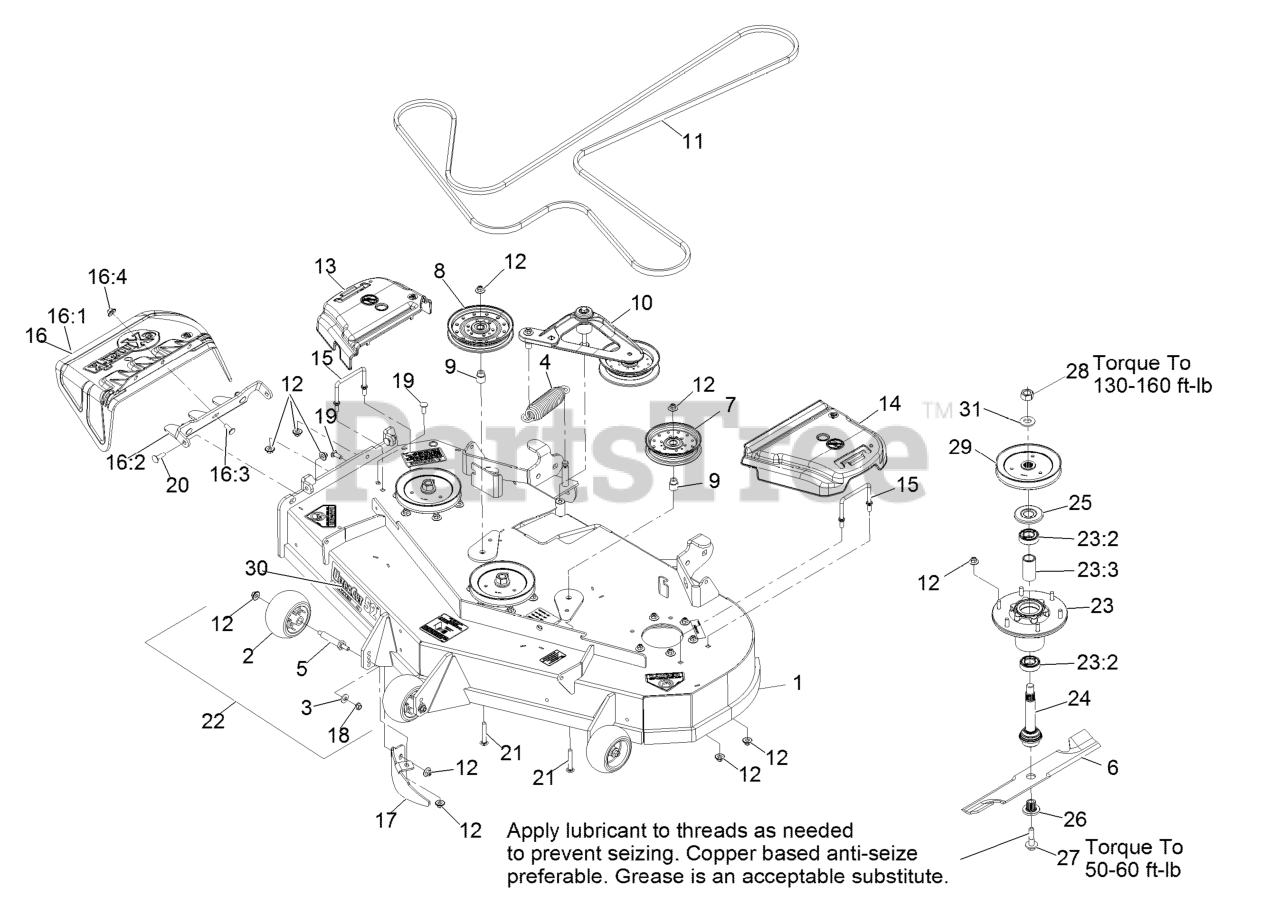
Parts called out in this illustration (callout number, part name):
1	ASM,DECK W/ DECALS 52
2	ROLLER-SCALP, ANTI
3	WASHER-BELLEVILLE
4	SPRING-EXTENSION
9	BUSHING-IDLER
10	DECK IDLER ASM
11	BELT,V-B X 186.00"
12	Nut-Nyloc 3/8-16 Flg
13	COVER-BELT, RH
14	COVER-BELT, LH
15	WIREFORM-COVER
16	ASM,DISCHARGE CHUTE
16:1	CHUTE,DISCHARGE
16:2	BRACKET,DISCHARGE CHUTE
16:3	SCREW-CARR
16:4	Nut-Nyloc 3/8-16 Flg
17	BAFFLE-DOGLEG, LZ-VT52
18	NUT-HHF, WHIZ
19	SCREW-CARR
20	Bolt-Carriage 3/8-16 X 1 1/4
21	SCREW-CARR
23	ASM-CUTTER HSG WITH BEARINGS
23:2	BEARING-BALL
23:3	SPACER-BEARING
24	ASM-SPINDLE AND SEAL
25	GUARD,BEARING TOP .989
26	BUSHING,SPLINED
27	SCREW,SEMS 1/2-20 X 2.19
28	NUT-HEX
29	SHEAVE,BLADE DRIVE 6.50
30	DECAL,ULTRACUT 52 SERIES
